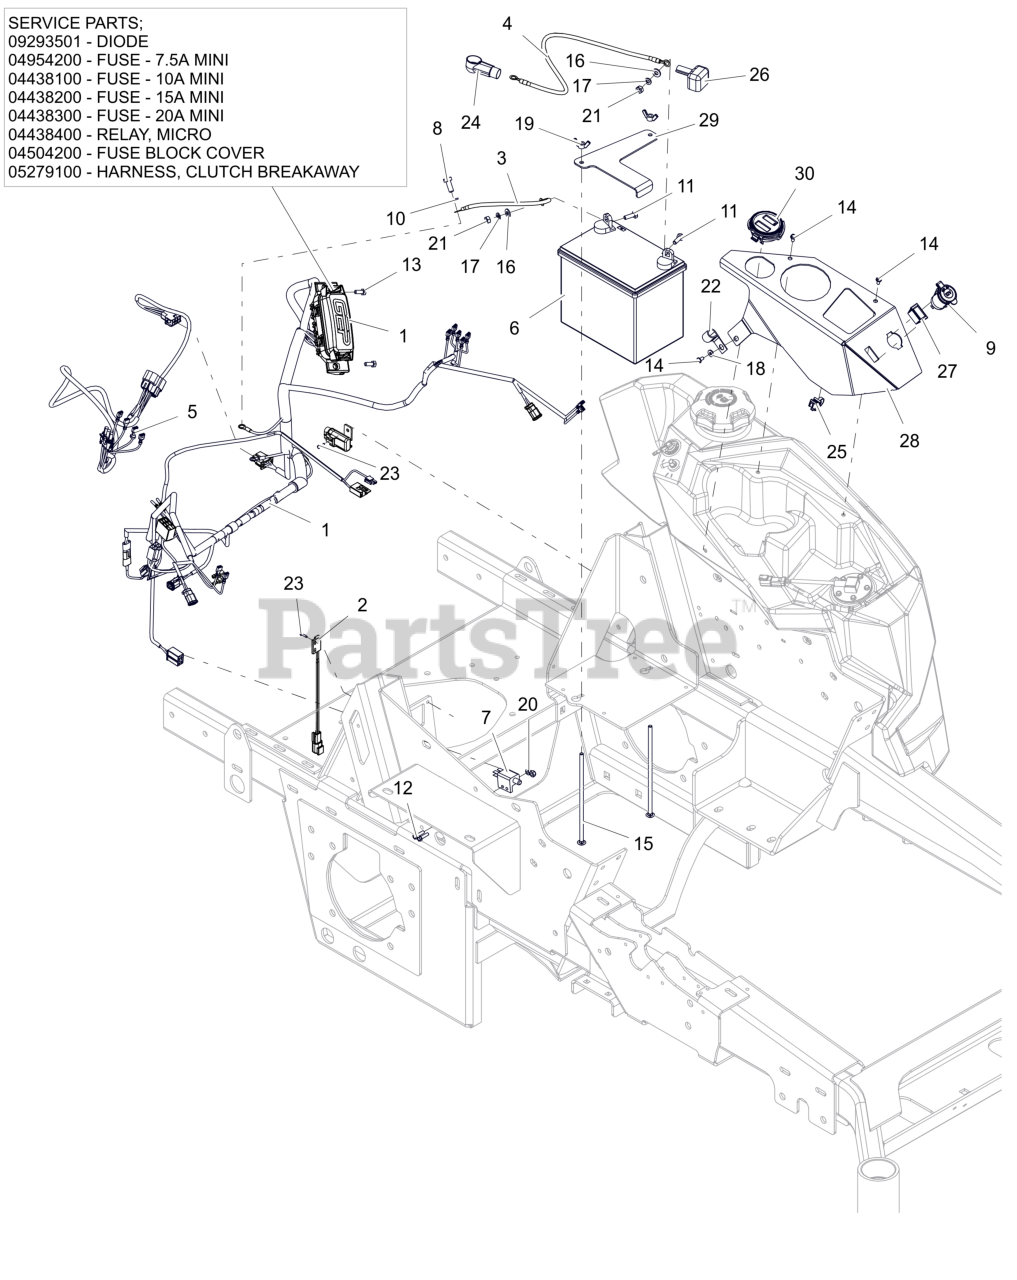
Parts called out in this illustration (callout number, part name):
1	HARNESS, ELECTRICAL 421
1	DIODE, CONNECTOR SHELL
1	FUSE, 7.5 AMP MINI-ATC
1	FUSE,10 AMP MINI-ATC
1	FUSE,15 AMP MINI-ATC
1	FUSE,20 AMP MINI ATC
1	RELAY,MICRO5 TERML W/RESISTOR
1	COVER, HARNESS FUSE/RELAY MOD
1	HARNESS, CLUTCH BREAKAWAY
2	SWITCH, MAGNETIC
3	CABLE, NEGATIVE BATTERY 11.5 LNG
4	CABLE, POS W/(2) .312 RING 16.0 LG
5	HARNESS, PT600 EFI ADAPTER
6	BATTERY, 300 CCA 10U1L
7	SWITCH- DOUBLE POLE N.O./N.O.
8	BLT, HEX M8-1.25X20 G8.8 ZCC
9	PORT, 12 VOLT POWER
10	WSHR,LK-REG .312X.078 ZCC
11	BLT, HEX .25-20X.75 G5 ZCC
12	BLT, HWH #10-24X.75 ZCC
13	BLT, HEX M6-1X16 G8.8 ZCC
14	SCR-MCH 10-24X.38 HWHSTAINLESS
15	BTL,RHSN .250-20 X 7.5 G5 ZCC
16	WSHR,FLT .281X.625X.065 ZCC
17	WSHR,LK-REG .250X.062 ZCC
18	WSHR-FL-STL .196X.50X.06 ZC120
19	NUT, LK-WING .25-20 ZCC
20	NUT-LK-NYL #10-24 G2 ZCC
21	NUT-STD .250-20 G2 ZCC
23	SCR-TAP #4-40X.50 HWH ZCC
24	BOOT, .65ID POS
25	TIE, EC23 MOUNT W CABLE
26	INSULATOR
27	SWITCH,BLANK
28	PANEL, LH CONTROL (RED)
29	HOLDDOWN, BATTERY (BLACK)
30	DUAL METER
